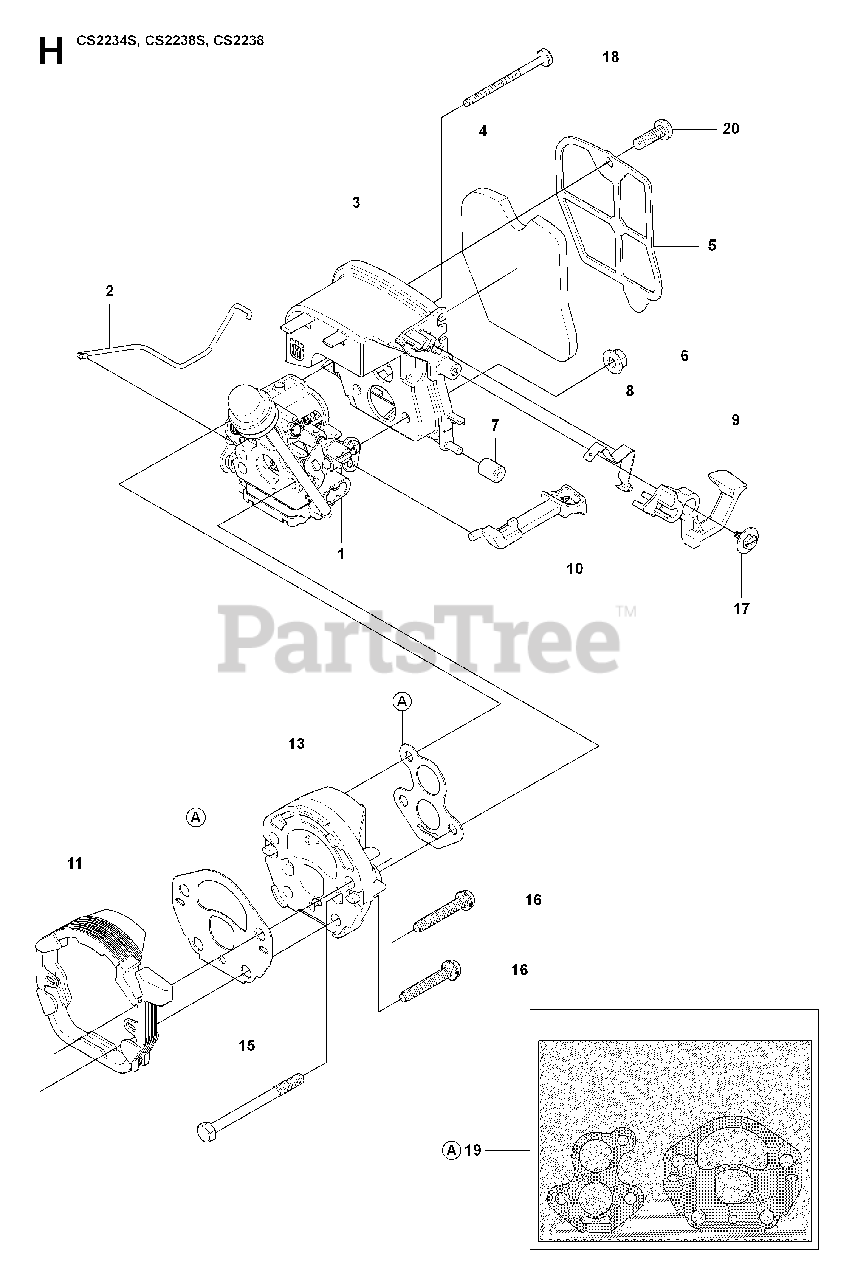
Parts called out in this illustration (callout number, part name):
1	%CARBURETOR
2	THROTTLE WIRE
3	FILTER HOUSING
4	AIR FILTER
7	ISOLATOR FILTER HOUSING
9	SWITCH LEVER
10	CHOKE KNOB
11	CARB ADAPTOR SEAL
13	CARB ADAPTOR
15	STUD CARBURETOR
18	TOP STUD - CARBURETOR
19	GASKET KIT
20	SCREW FILTER PLATE
